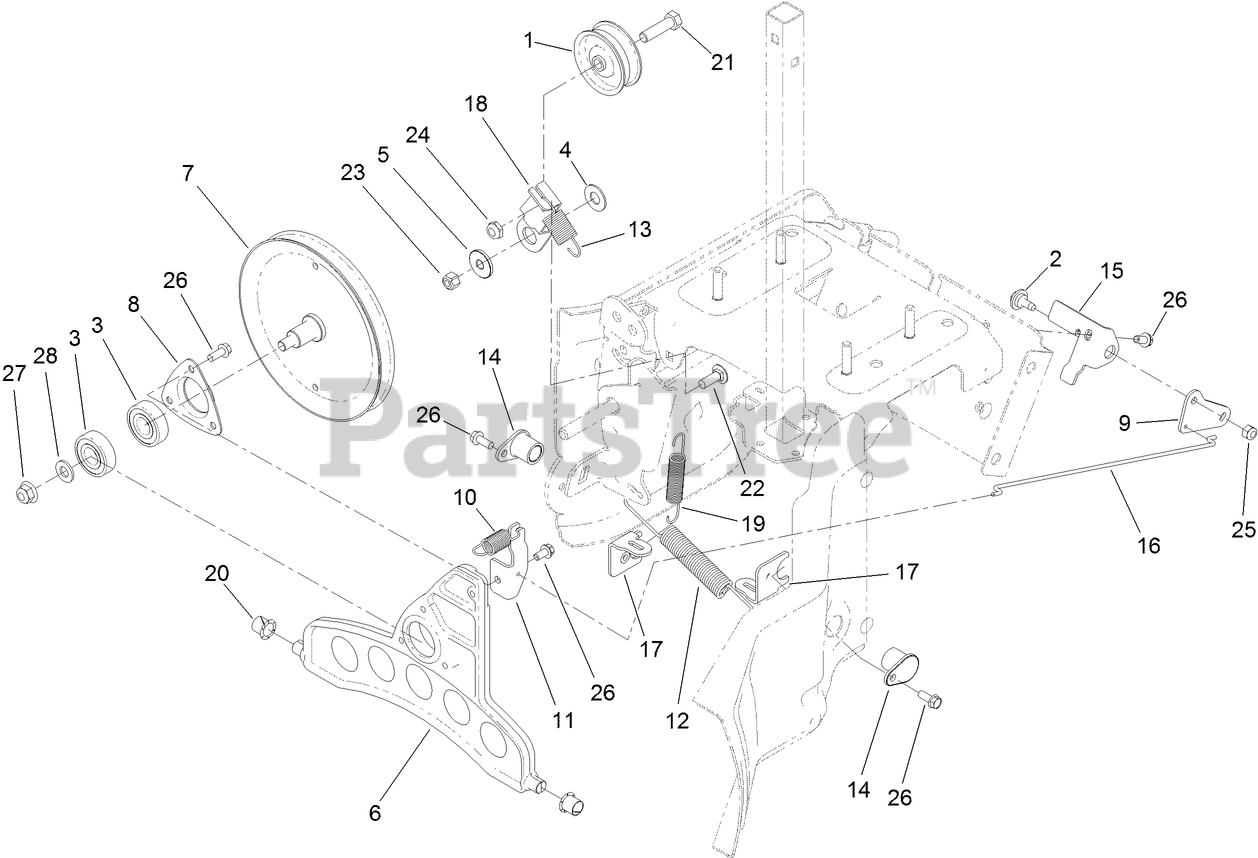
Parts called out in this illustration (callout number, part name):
1	PULLEY-IDLER
2	SCREW-SHOULDER
3	BEARING-BALL
4	WASHER
5	BUSHING-IDLER
6	PLATE-WHEEL, FRICTION
7	TRACTION PULLEY ASM
8	RETAINER-BEARING
9	BELLCRANK-DRIVE
10	SPRING-EXTENSION
11	BRACKET-PLATE, TRACTION
12	SPRING-EXTENSION
13	SPRING-EXTENSION
14	BUSHING-PLATE, TRACTION
15	BRACKET-BELLCRANK
16	LINK-DRIVE
17	BRACKET-ANCHOR, SPRING
18	ARM-IDLER, TRACTION
19	SPRING-EXTENSION
20	BUSHING-NYLINER
21	SCREW-HH
22	BOLT-CARR
23	NUT-HEX
24	NUT-HEX
25	NUT-HEX
26	SCREW-HWH
27	NUT-HF, NI
28	WASHER-FLAT
